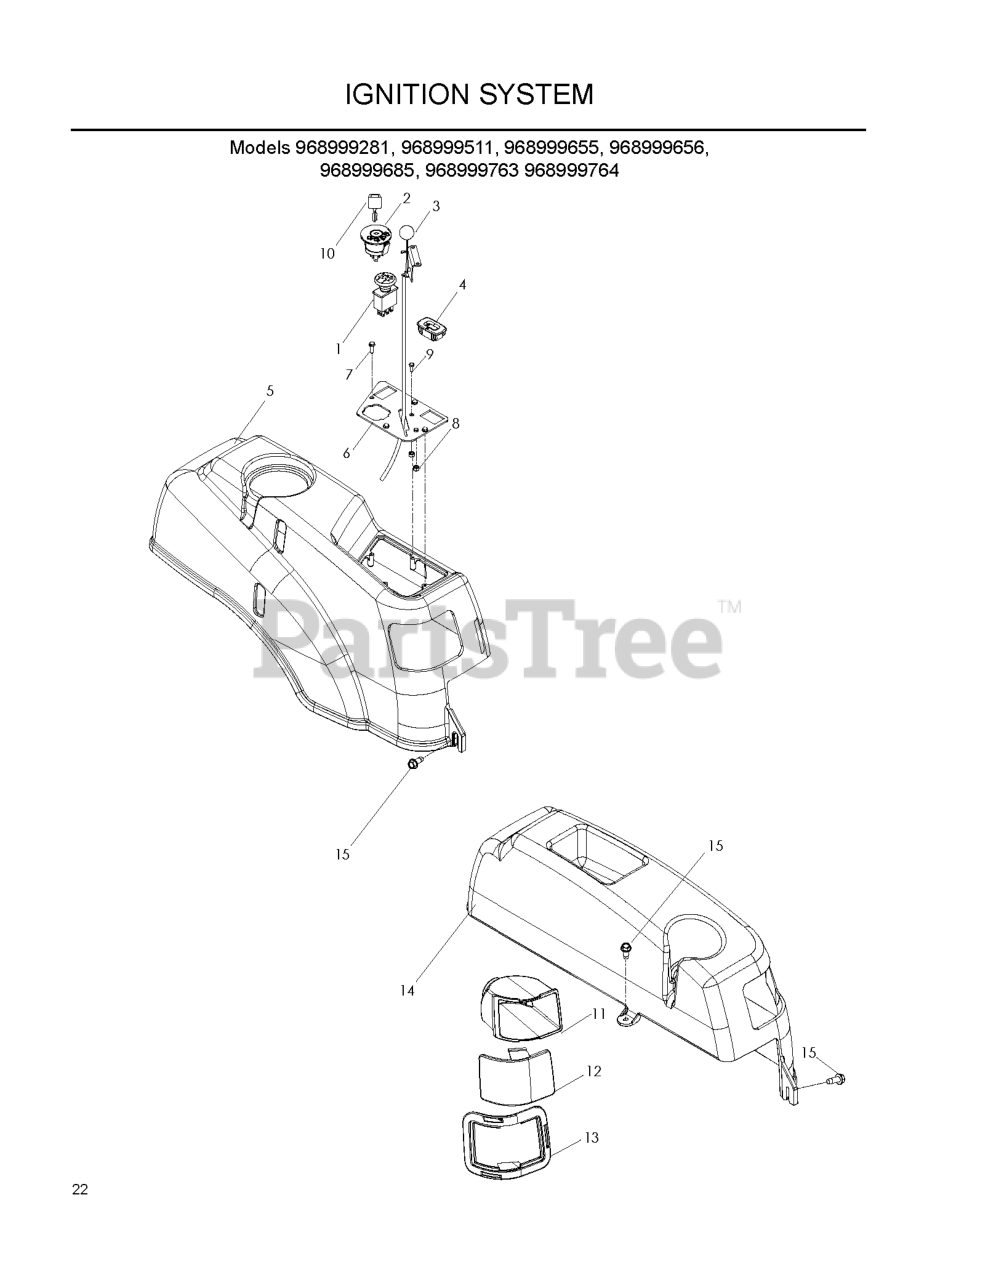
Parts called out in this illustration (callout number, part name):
1	RP.SWITCH, BLADE
2	RP IGNITION SWITCH
3	THROTTLE CABLE DETENT
4	HOUR METER
5	RP.FENDER, RT
6	PLATE.CONTROL.CONSOLE.BLACK
7	SCR #10-12X3/4 HEX WAS HD ZD
8	NUT 10-24 NYLOC
9	HCS #10-24 X 1/2
10	KEY
11	RT HEADLIGHT REFLECTOR
11	LEFT HEADLIGHT REFLECTOR
12	LENS, COLORED LEFT
12	LENS, COLORED RIGHT
13	LEFT HEADLIGHT RIM GREY
13	RT HEADLIGHT RIM GREY
14	FENDER, LT
15	SCREW 1/4 X 5/8
